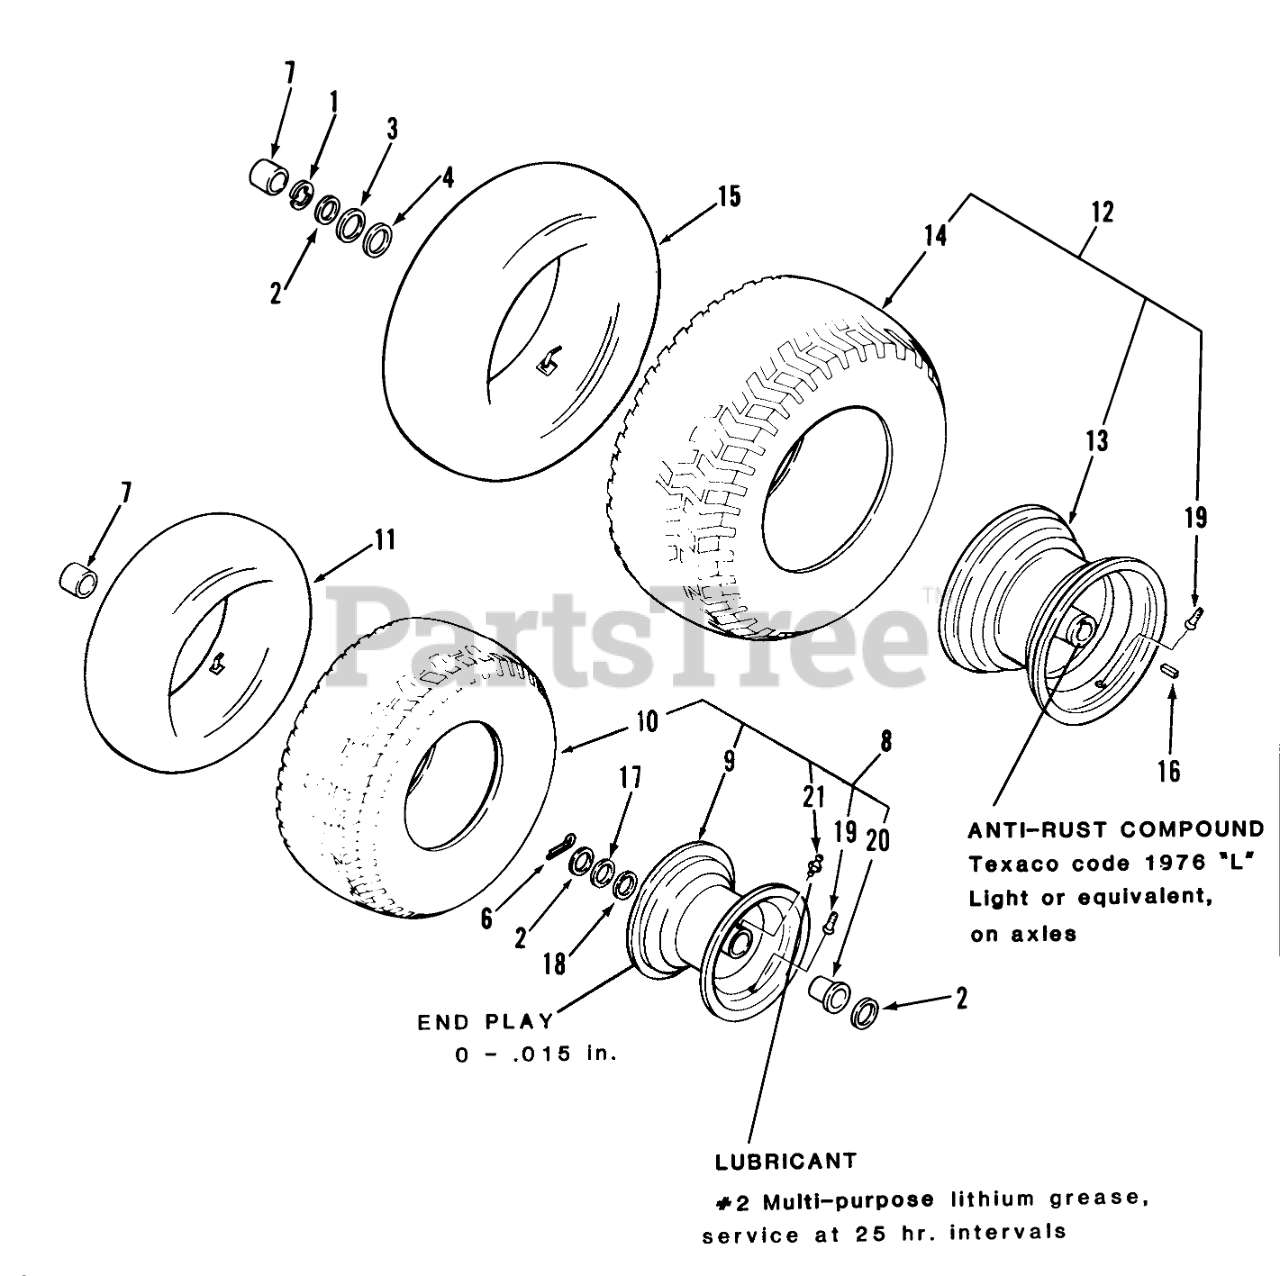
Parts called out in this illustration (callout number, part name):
1	E Ring
2	WASHER-FLAT
3	WASHER-SHIM
4	WASHER
6	COTTER PIN-4
7	HUB CAP
8	Assy-Wheel & Tire Front LT-832 Only
8	Assy-Wheel & Tire Front 5-Speed Only
9	Front Wheel LT-832 Only
9	Front Wheel 5-Speed Only
10	Tire-Front 13 X 5.00-6
10	Front Tire 13 x 6.50-6-5-Speed Only
11	Front Tube-Service Only
11	Tube (Service Only)
12	Coil Spring
12	Assy-Wheel & Tire-Rear 5-Speed Only
13	WHEEL ASSY
13	Rear Wheel 5-Speed Only
14	TIRE
14	Rear Tire 20 x 10.0-10.0
15	Rear Tube-Service Only
16	SQ KEY
17	WASHER
18	WASHER-SHIM
19	VALVE
20	FLANGE BEARING
21	Zerk
21	ZERK-GREASE
